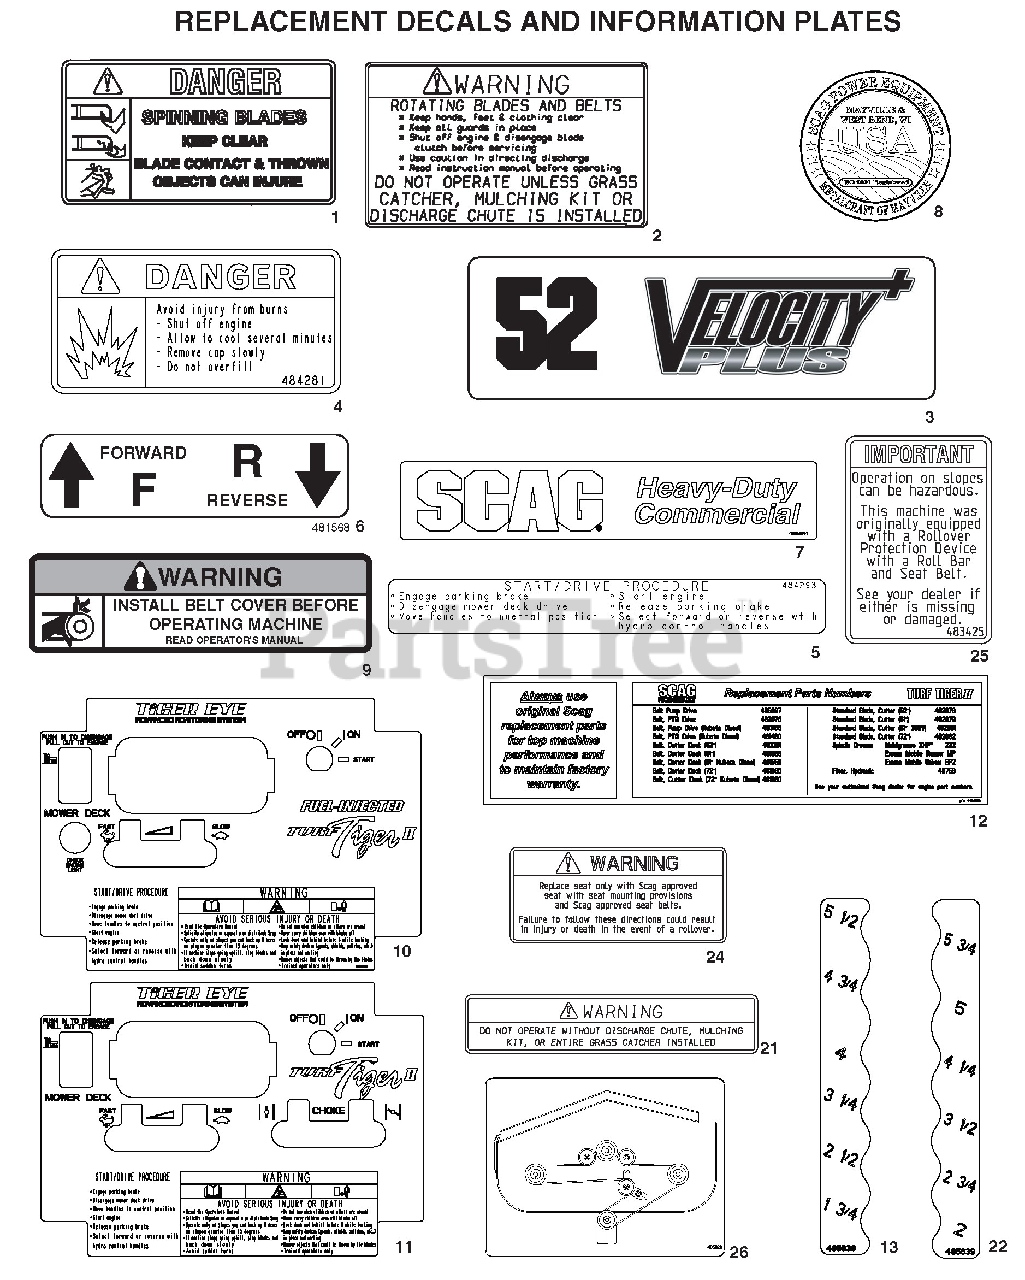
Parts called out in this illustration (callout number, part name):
1	Decal, Danger - Spinning Blades
2	Decal, Warning - Rotating Blades
3	Decal, 52 Velocity Plus
3	Decal, 61 Velocity Plus
3	Decal, 72 Advantage
3	Decal, 72 Velocity Plus
4	Decal, Fuel Tank
5	Decal, Start / Drive
6	Decal, Traction Control
7	Decal, Heavy-Duty Commercial
8	Decal, Metalcraft - USA
9	Decal, Belt Cover
10	Decal, Instrument Panel - Fuel Injected
11	Decal, Instrument Panel
12	Decal, STTII Replacement Parts
13	Decal, Cutting Height - LH
21	Decal, Warning
22	Decal, Cutting Height - RH
24	Decal, Seat Replacement
25	Decal, ROPS
26	Decal, Belt Routing
